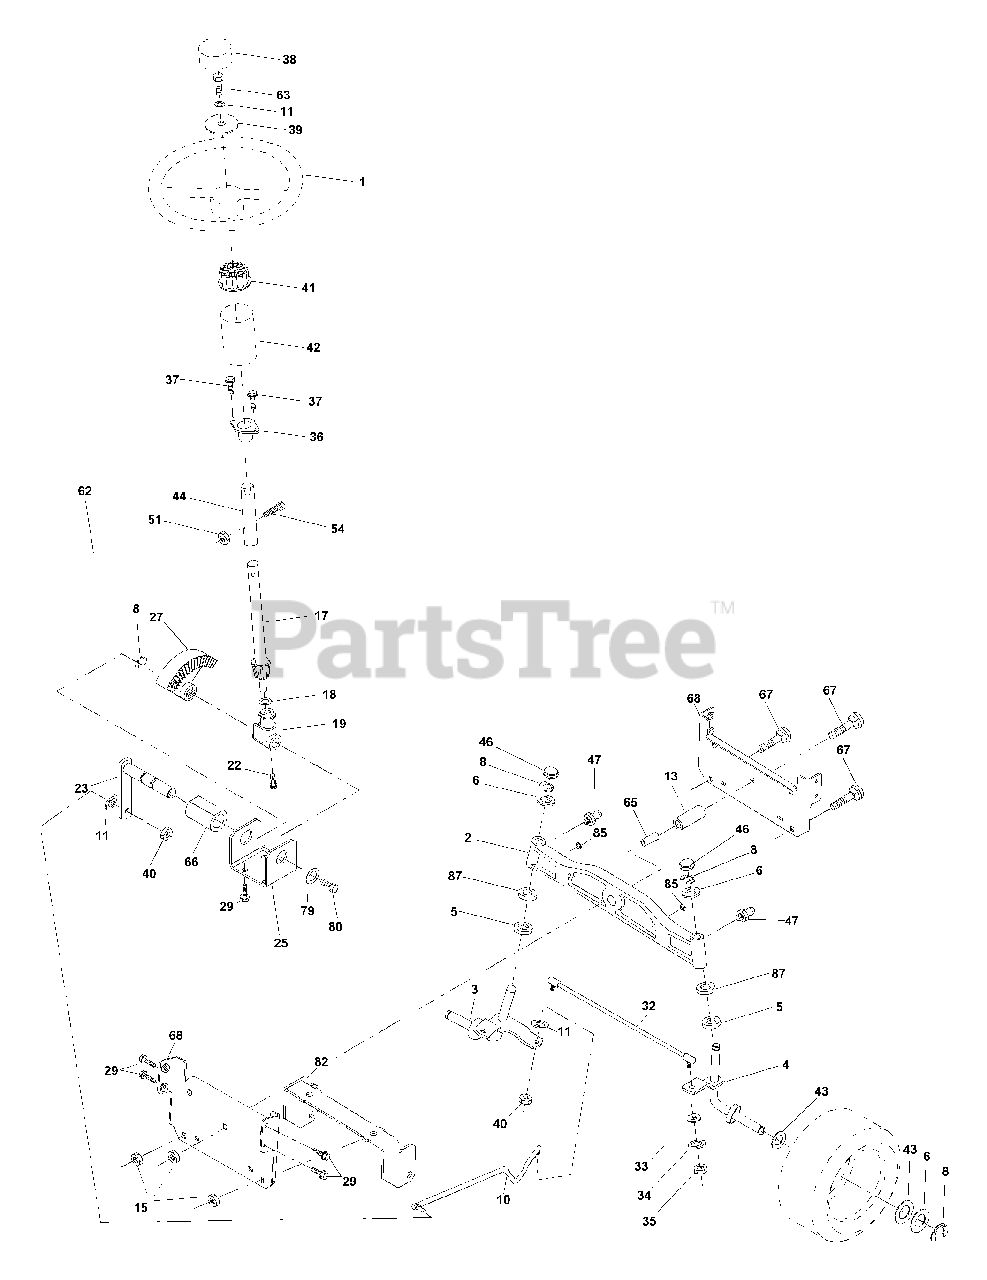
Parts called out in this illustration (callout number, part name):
1	Wheel Steering
2	Axle Cast Lt Machined
3	Spindle Asm LH
4	Spindle Asm RH
5	Bearing Race Thrust Harden
6	Washer 25/32 X 1-5/8 X 16 Ga
8	Ring Klip #t5304-75
10	Link Drag
11	Washer Lock Hvy Hlcl Spr 3/8
13	Spacer Brg Axle Front
15	Nut Hex Flange Lock
17	Shaft Asm Strg Private Label
18	Washer Thrust 515x 750x 033
19	Support Shaft
22	Screw Hex Wsh Hd Torx
23	Shaft Asm Pittman
25	Bracket Steering
27	Gear Sector 22 Teeth
29	Screw 3/8-16x3/4
32	Rod Tie
33	Washer 11/32 x 3/4 x 16 Ga.
34	Washer Lock Hry Hlcl Spr 5/16
35	Nut Crownlock 5/16 - 24 UNF
36	Bushing Strg
37	Screw TT #32.5 x 5 x 3/8 Flange
38	Cap Wheel Steer
39	Washer 13/32 x 1-1/20 x 11 Ga
40	Nut Lock Center 3/8-24 Unf
41	Adaptor Wheel Strg
42	Boot Dash Steering
43	Washer 25/32 X 1 1/4 X 16 Ga
44	Extension Steering Non-adjust
46	Cap Spindle Fr Top Blk
47	Fitting Grease
51	Nut Lock Hex W/Ins 5/16-18 UNC
54	Bolt Fin Hex 5/16-18 UNC x 1-1/4
62	Steering Assembly
63	Bolt Fin Hex 3/8-16 UNC x 1 Gr. 5
65	Spacer Brace Axle
66	Bearing Arm Pittm-an
67	Bolt Rdhd Sqn 3/8-16 x 2-1/4
68	Brace, Axle
79	Washer 13/32 x 1-1/4 x 12 Ga.
80	Bolt Hex Nylon 3/8-16 x 3/4
82	Bracket Susp Chassis Front
85	Fastner Christmas Tree
87	Washer Flat .781 x 1-1/2 x .14
